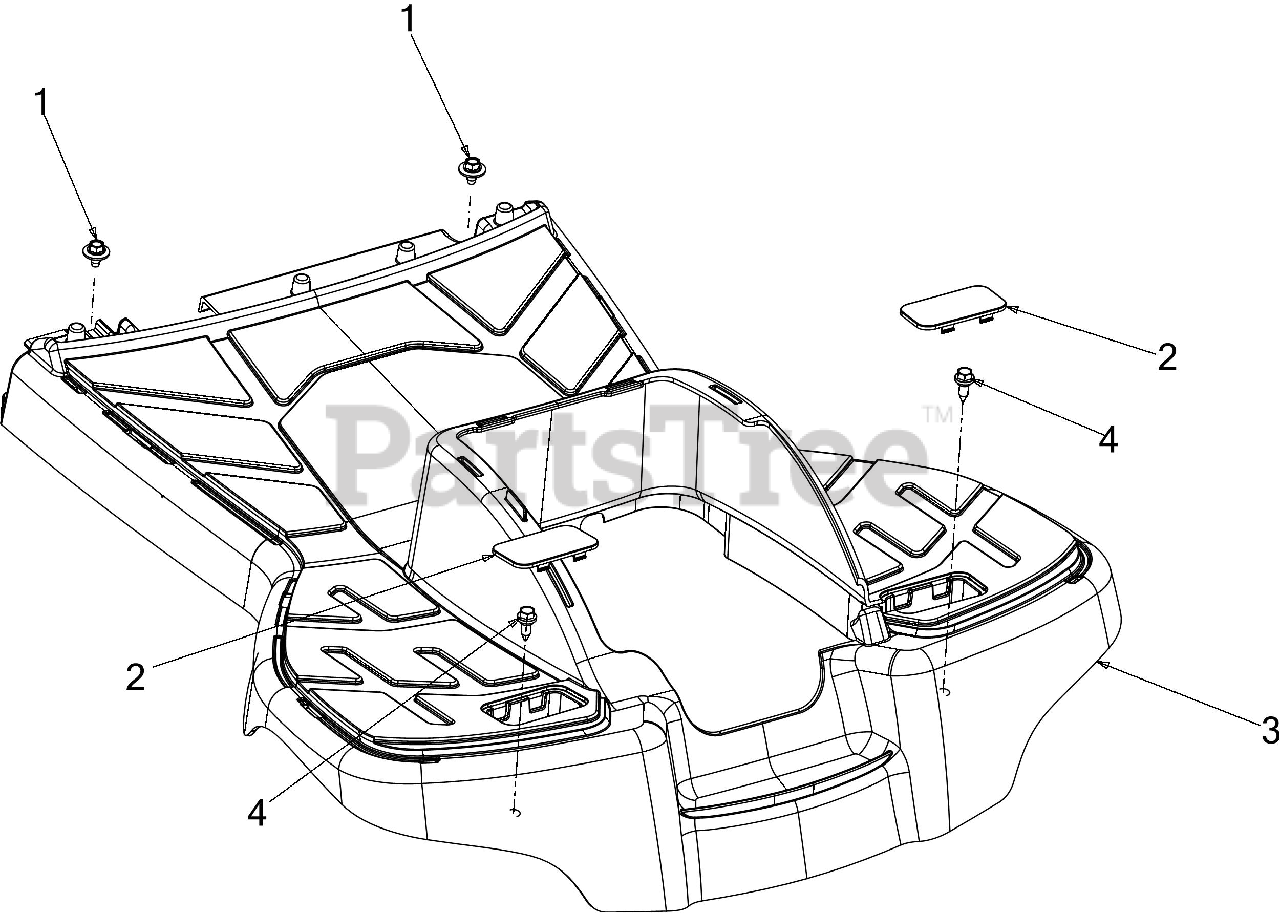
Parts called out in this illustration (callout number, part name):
1	SCREW 1/4-20 x .50
2	RUNNING BOARD PLUG
3	RUNNING BOARD
4	SHOULDER SCREW
